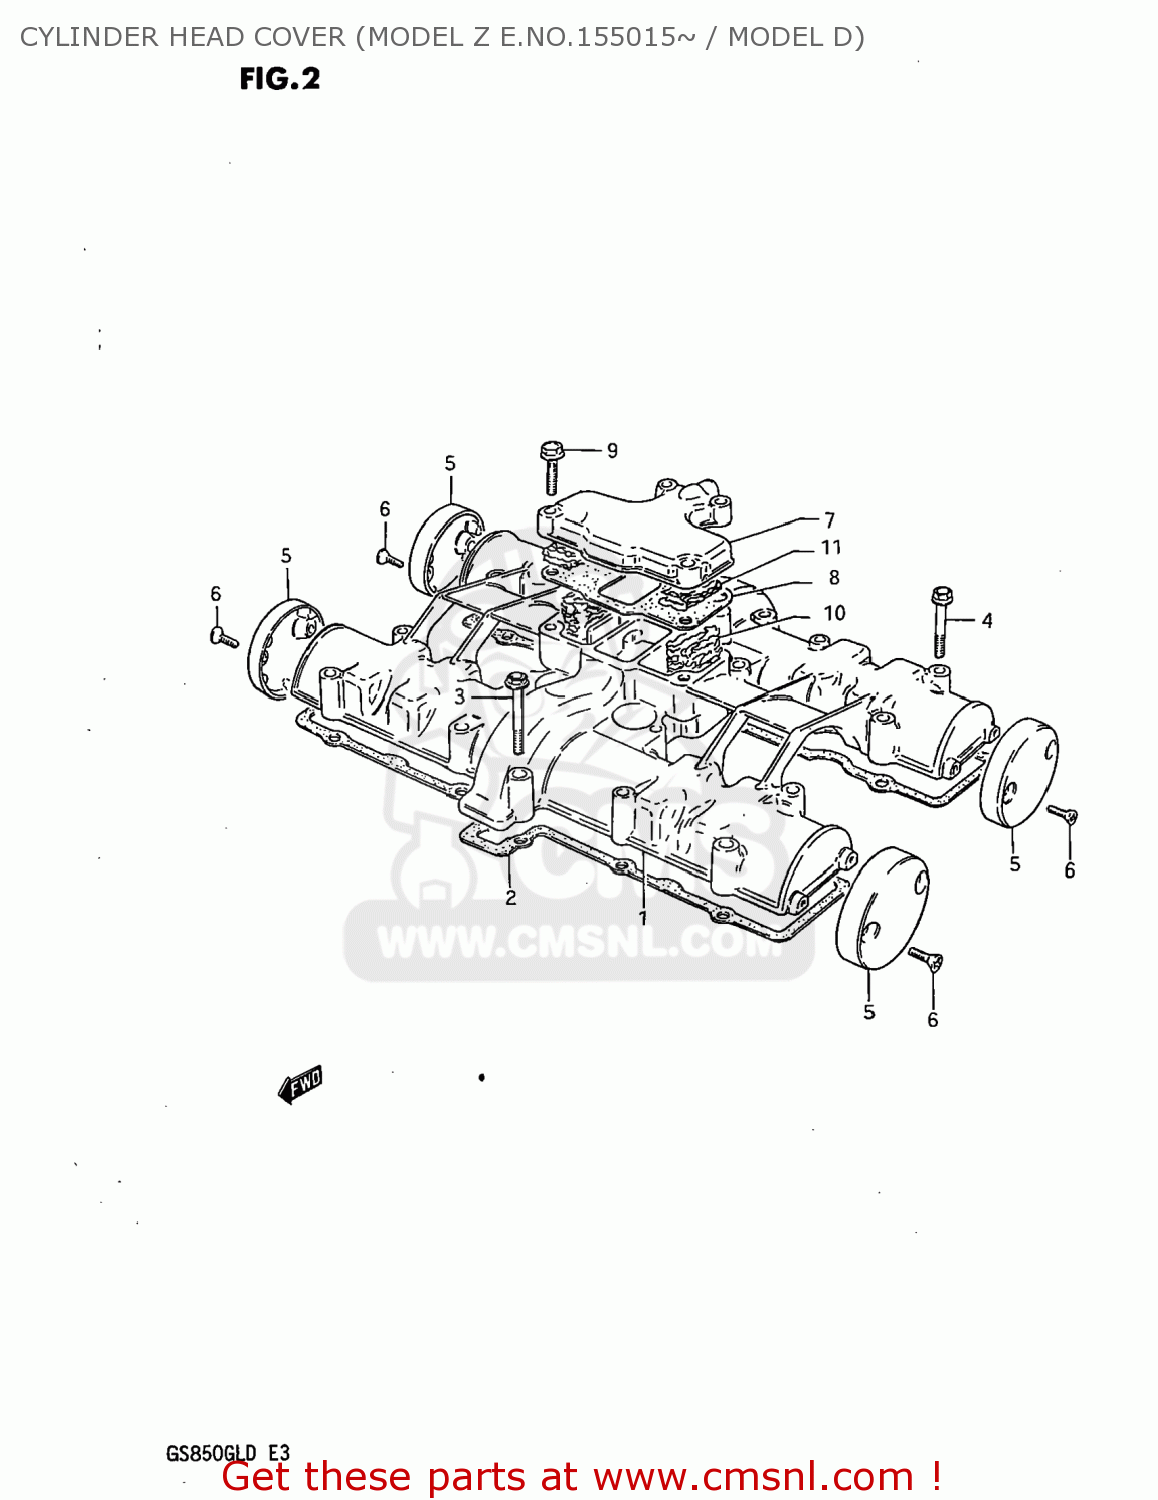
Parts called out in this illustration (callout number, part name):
1	COVER,CYLINDER
2	GASKET,CYLINDER HEAD COVER (MCA)
3	BOLT
4	BOLT,UNDER
5	CAP,CYLINDER HEAD COVER
6	SCREW(5X12)
7	COVER,BREATHER
8	GASKET (MCA)
9	BOLT
10	COVER,BREATHER
11	SEPARATOR,OIL BREATHER
